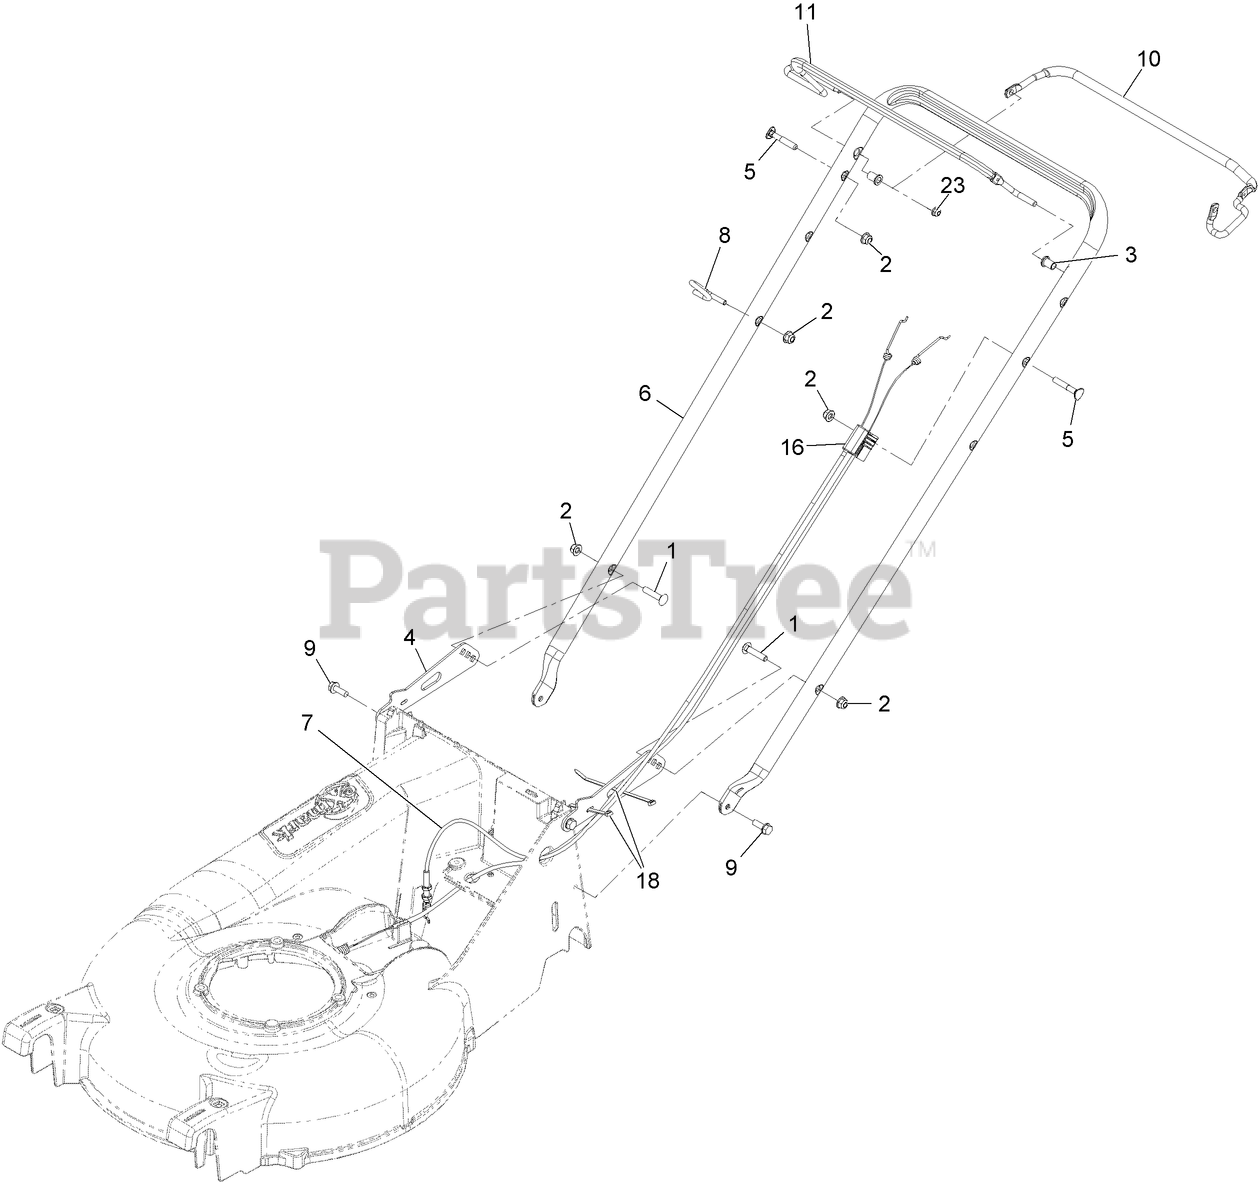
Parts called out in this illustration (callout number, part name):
1	BOLT-CARR
2	NUT-HF, NI
3	BUSHING-HANDLEBAR
4	BRACKET,HANDLEBAR
6	HANDLEBAR-P21
7	CABLE, DRIVE EC21
8	GUIDE,ROPE
9	SCREW-TAPTITE
11	BAIL,OPC/BBC
16	CABLE-ZONE KAWASAKI
18	TIE-CABLE
